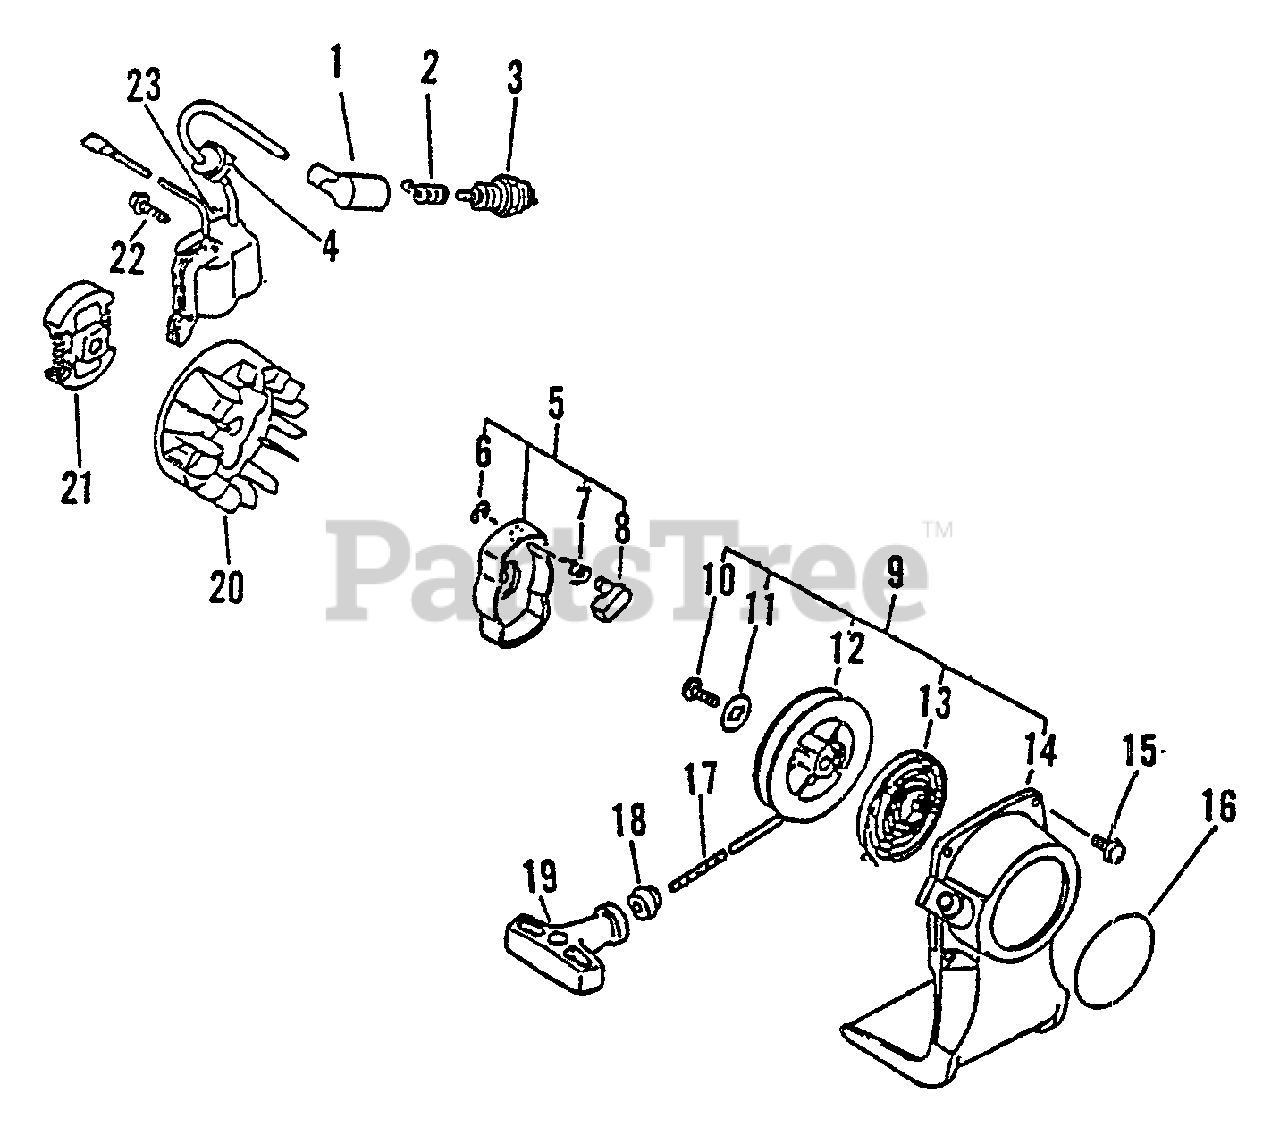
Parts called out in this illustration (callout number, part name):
1	CAP, SPARK PLUG
2	TERMINAL, SPARK PLUG
3	SPARK PLUG - BPM7A
5	STARTER PAWL ASSY
6	E-RING 4
7	SPRING, RETURN
8	PAWL, STARTER
9	STARTER ASSY
11	WASHER
12	REEL, ROPE
13	SPRING, RECOIL
14	CASE, STARTER - BLUE
15	SCREW 4×16
17	ROPE, STARTER
18	GUIDE, ROPE
19	GRIP, STARTER
20	FLYWHEEL
21	CLUTCH ASSY
22	SCREW 4×22
23	COIL, IGNITION
